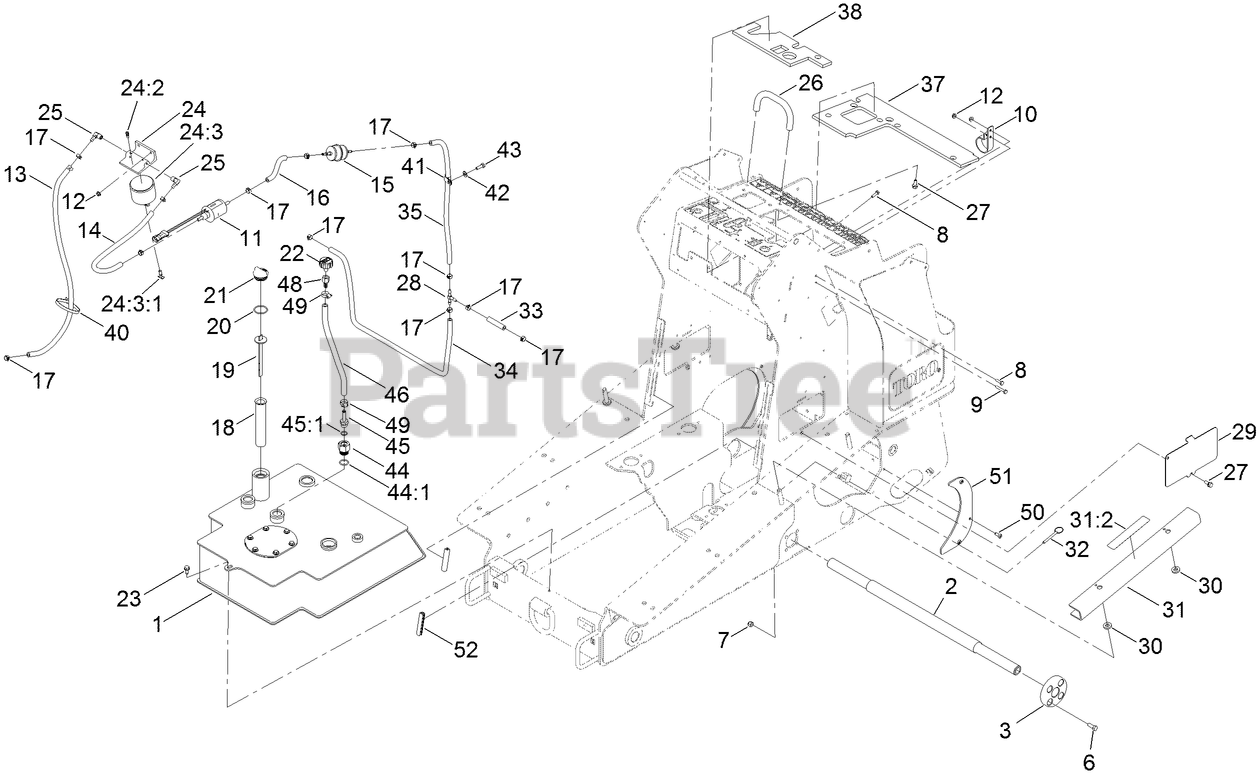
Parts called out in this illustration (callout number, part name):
1	TANK-HYD
2	SHAFT-TRACK
3	HUB-SHAFT
6	SCREW-HH
7	NUT-LOCK, NI
8	SCREW-HH
9	SCREW-HH
10	BRACKET-PUMP, FUEL
11	PUMP-FUEL
12	NUT-HF
13	HOSE-FUEL
14	HOSE-FUEL
15	FILTER-INLINE
16	HOSE-FUEL
17	CLAMP-HOSE
18	FILTER-SCREEN
19	DIPSTICK
20	O-RING
21	PLUG-PLASTIC
22	BREATHER
23	SCREW-THD ROLL, HWH
24	FILTER HEAD ASM
24:2	VENT-AIR
24:3	ELEMENT-SPIN ON
24:3:1	VALVE-DRAIN
25	FITTING-HYD, 90
26	BAR-REFERENCE
27	SCREW-HHF
28	FITTING-TEE, BARBED
29	PLATE-COVER, ACCESS
30	WASHER-NEOPRENE
31	ARM-LOCKING
31:2	DECAL-DANGER
32	PIN-COTTERLESS
33	HOSE-FUEL
34	HOSE-FUEL
35	HOSE-FUEL
37	FOAM-HEAT SHIELD
38	FOAM-HEAT SHIELD
40	TIE-CABLE
41	CLAMP-R
42	WASHER-FLAT
43	SCREW-HH
44	FITTING-STRAIGHT
44:1	O-RING
45	FITTING-STR
45:1	O-RING
48	FITTING-FEMALE, BARBED
49	CLAMP-HOSE
50	PLATE-DIRT
51	SCREW-BHTF
